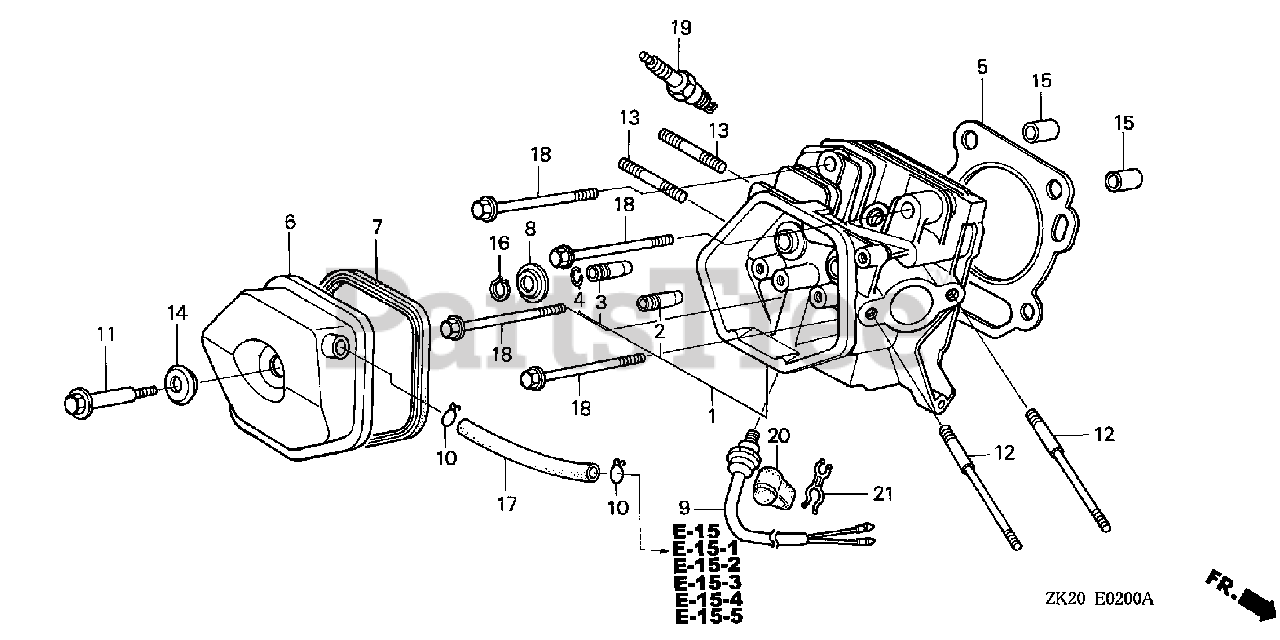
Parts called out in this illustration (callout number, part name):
1	CYLINDER HEAD
2	GUIDE, VALVE (OS)
3	GUIDE, EX. VALVE (OS)
4	CLIP, VALVE GUIDE
5	GASKET, CYLINDER HEAD
6	COVER, HEAD
7	GASKET, CYLINDER HEAD COVER
8	SEAT, VALVE SPRING
11	BOLT, HEAD COVER
12	BOLT, STUD (8X123)
13	BOLT, STUD
13	BOLT 2, STUD (8X32)
14	WASHER, HEAD COVER
15	PIN A, DOWEL (12X20)
17	BULK HOSE, VACUUM (11X1000) (11X100)
17	BULK HOSE, VACUUM (11X1000) (11X105)
18	BOLT, FLANGE (10X80)
19	SPARK PLUG (BPR5ES) (NGK)
19	SPARK PLUG (W16EPR-U) (DENSO)
19	SPARK PLUG (BPR6ES) (NGK)
19	SPARK PLUG (W20EPR-U) (DENSO)
